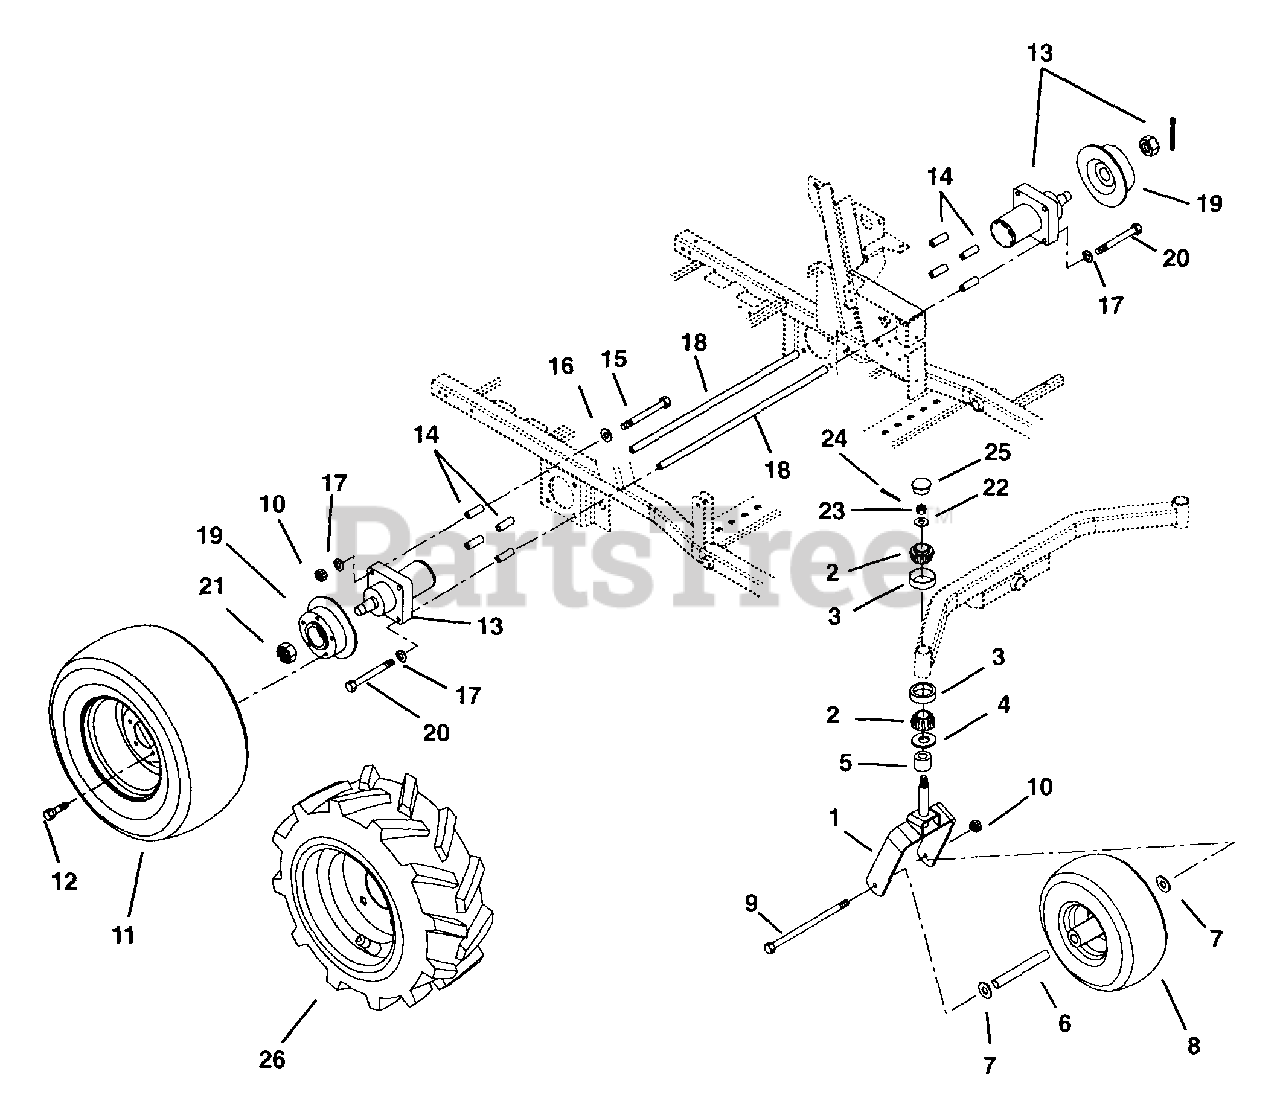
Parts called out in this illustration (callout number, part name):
1	Fork-Front
2	Bearing-Cone w/ Grease
3	Bearing-Cup 1.980 x .420
4	Bearing Seal 1.5 x 2 x .18
5	Spacer, PM, 1.03 I.D. x 1.5 O.D. x .375
6	Spacer-Wheel
7	Washer-Flat-Steel .515 x 1.625 x .250
8	Wheel/Tire 15 x 6 - 6
9	Bolt-Hex .50-13 x 9.00 Grade 5
10	Nut-Locking-Center .50-13
11	Wheel-Tire 23 x 10.50 - 12 Multi-Trac
11	Tire 23 x 10.50
11	Wheel-Tire Assembly 23 x 10 50-12
11	Wheel-Tire 23 x 8.50 Multi-Trac
11	Tire 23 x 8.50
12	Bolt-Lug .50-20 x 1.62
13	Hydraulic Wheel Motor
14	Bushing-Sleeve .513 x .748 x 2.129
15	Bolt-Hex .50-13 x 5.00 Grade 5
16	Spacer .500 x .750 x .321
17	Washer-Locking .50 x .125
18	Rod-Motor Connecting
19	Hub and Disc
20	Bolt-Hex .50-13 x 4.50 Grade 5
21	Nut -Lock Jam Patch
22	Washer-Flat-Steel .755 x 1.375 x .062
23	Nut-Slotted .75-16
24	Pin-Cotter .16 x 1.00
25	Cap-Dust
26	Wheel/Tire Kit, 260Z L. 8 R.
26	Wheel/Tire-L.H. 23 x 10.5-12 Tru Power
26	Wheel/Tire-R.H. 23 x 10.5-12 Tru Power
26	Wheel/Tire 23 x 10.50 - 12 Tru Power
